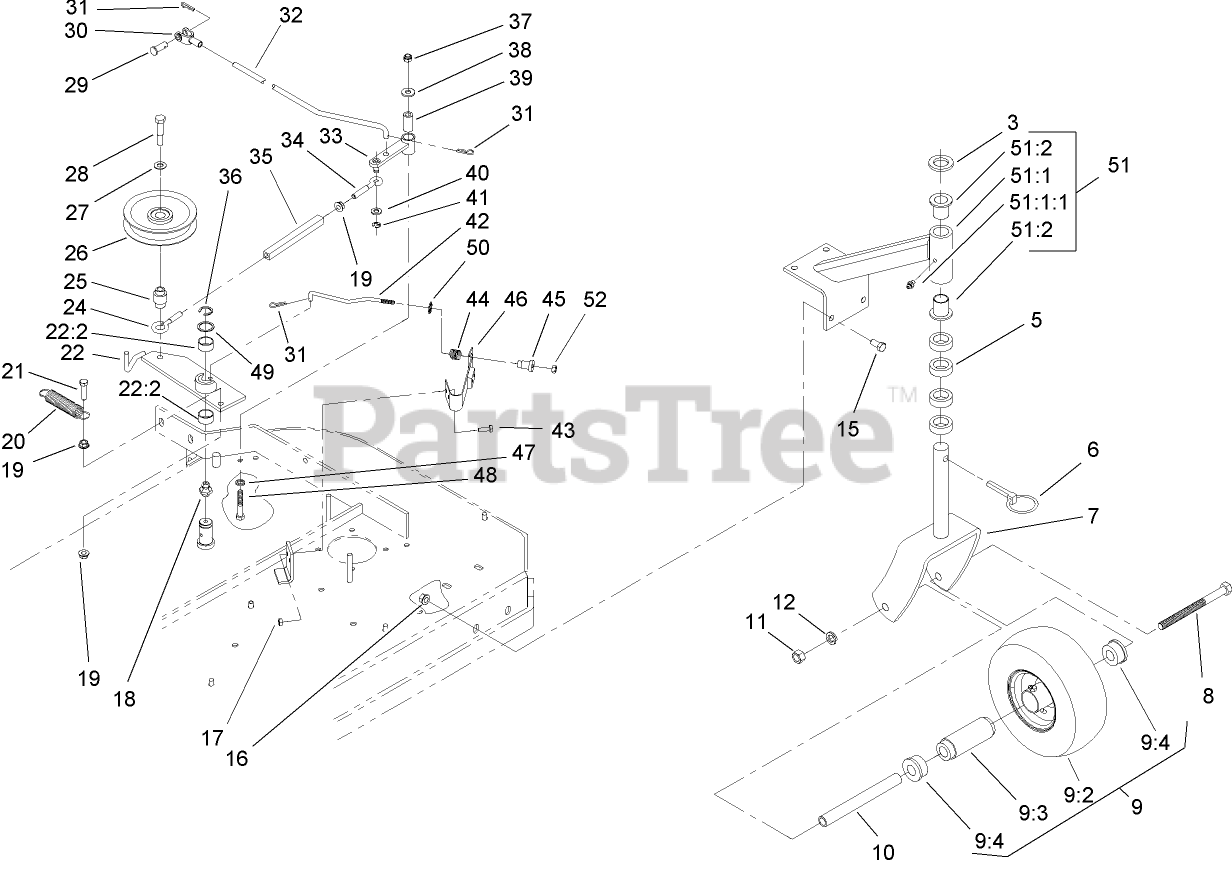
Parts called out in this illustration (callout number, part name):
3	WASHER-FLAT
5	SPACER-CASTER
7	FORK
8	SCREW-HH
9	WHEEL AND TIRE ASM
9:3	BEARING
9:4	BUSHING
10	SPACER
11	NUT-HH
12	WASHER-LOCK
15	SCREW-HH
16	NUT-HHF, WHIZ
17	NUT-LOCK, NI
18	FITTING-GREASE
19	NUT-HF
20	SPRING-EXTENSION
21	SCREW-HH
22	Idler Arm ASM
22:2	SLEEVE-BEARING
24	EYEBOLT-THREAD, LH
25	BUSHING-ENGAGEMENT
26	PULLEY-IDLER
27	WASHER-BELLEVILLE
28	SCREW-HH
29	PIN-CLEVIS
30	YOKE-ADJUSTABLE
31	PIN-COTTER
32	ARM-ASSIST, LINKAGE
33	ARM-ASSIST
34	EYEBOLT-THREAD, RH
35	BODY-TURNBUCKLE
36	RING-RETAINING, EXT
37	NUT-LOCK, NI
38	WASHER-FLAT
39	TUBE-PIVOT
40	WASHER-PLAIN
41	RING-RETAINING, EXT
42	ROD-BRAKE
43	SCREW-HH
44	SPRING-COMPRESSION
45	SPACER-FLANGED
46	PAD AND SPRING ASM
47	WASHER-SPRING
48	SCREW-HH
49	WASHER-SPINDLE
50	RING-PUSH ON
51	SUPPORT ASM
51:1	Support-Caster
51:1:1	FITTING-GREASE
51:2	BEARING-FLANGED
52	NUT-LOCK, NI
